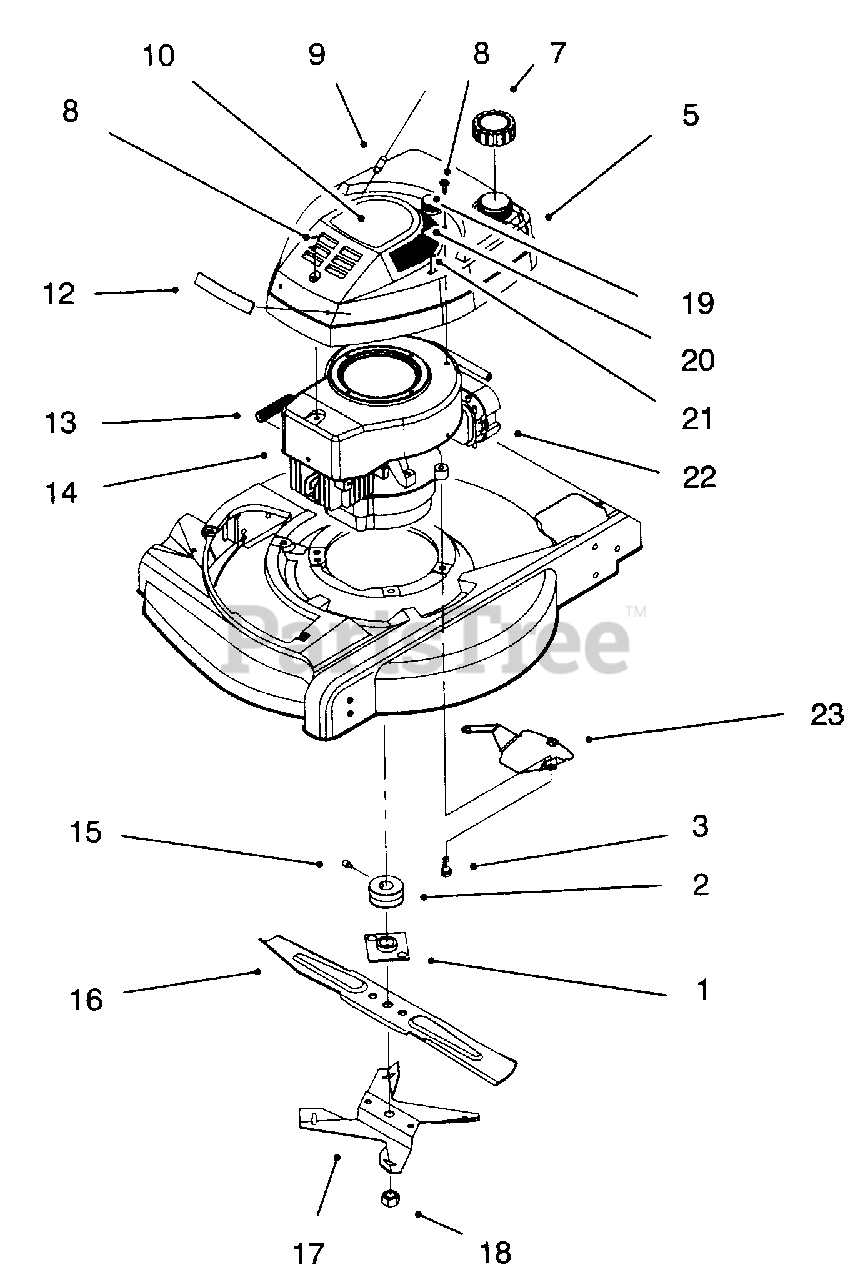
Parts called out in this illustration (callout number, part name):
1	Plate & Collar Assembly
2	Pulley-Engine (Model No. 10304 Only)
3	Screw-Engine
5	Tank & Shroud Assembly
7	Fuel/Oil Cap Assembly
8	Screw-Sems
9	Rope-Stop
10	Decal-Recoil (Model No. 10227 Only)
12	Applique-Shroud
13	Spring-Compression
14	Engine Assembly
15	Screw-Set (Model No. 10304 Only)
16	Blade-21"
17	Fan-Mulching
18	Nut-Blade
19	Bulb-Primer
20	Body-Primer
21	Hose-Primer
22	Line-Gas
23	Shield-Grass (Model No. 10304 Only)
